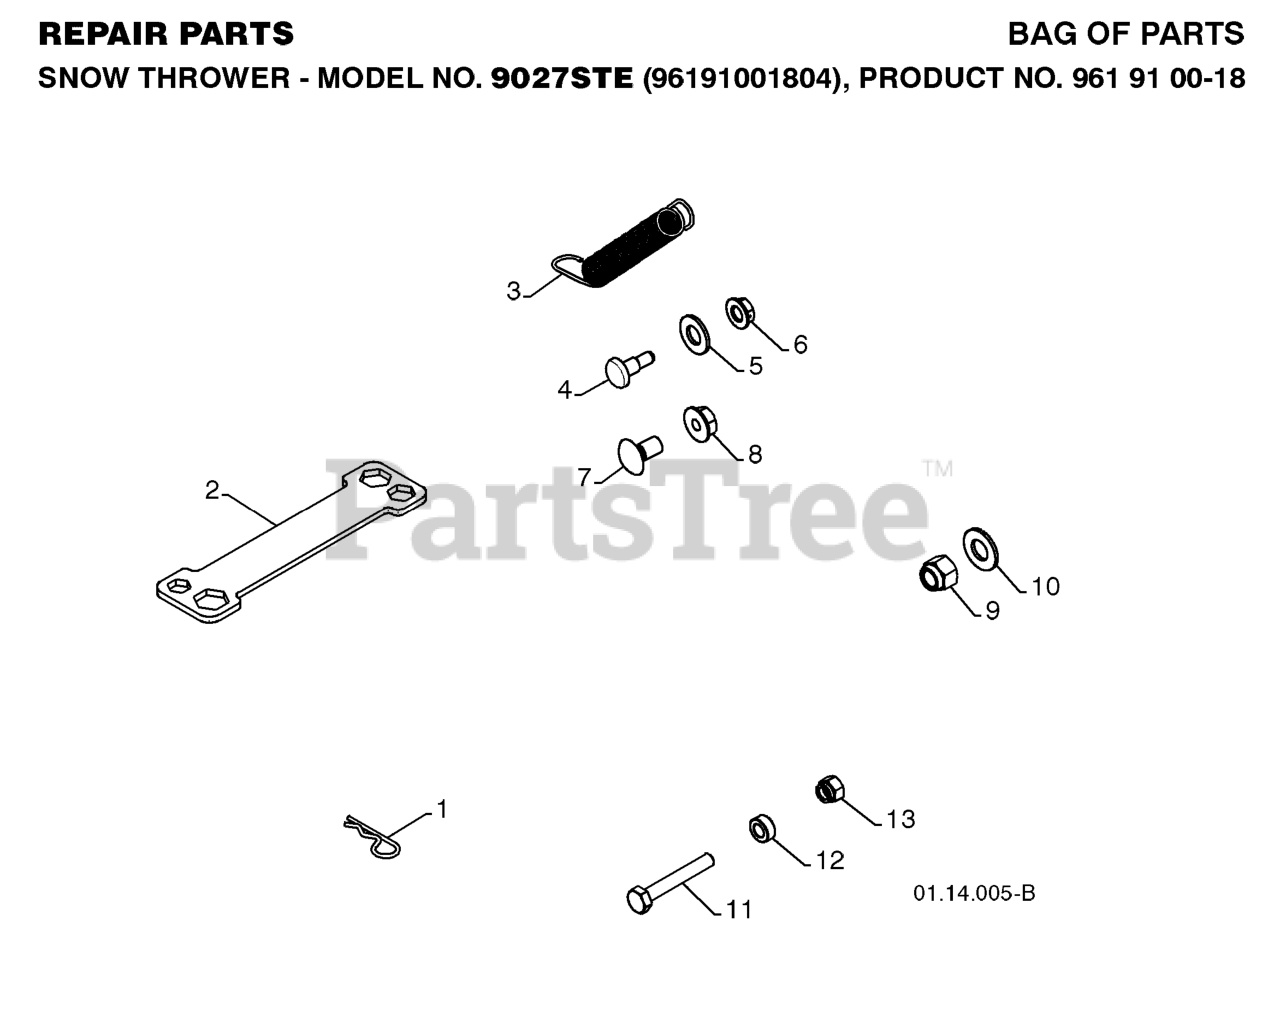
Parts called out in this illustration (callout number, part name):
1	SPRING RETAINER
2	RP WRENCH, SNOWTHROWER
3	SPRING.DEFLECTOR.REM.CHUTE
4	BOLT, SHOULDER
5	WASHER, NYLON FRICTION
6	NUT.HEX.FLANGE.1/4
7	BOLT
8	NUT.LOCK.5/16-18
9	NUT
10	WASHER
11	BOLT, SHEAR
12	SPACER.3943.SLEEVE.250X.47
13	LOCKNUT.NYLOC.1/4-20
